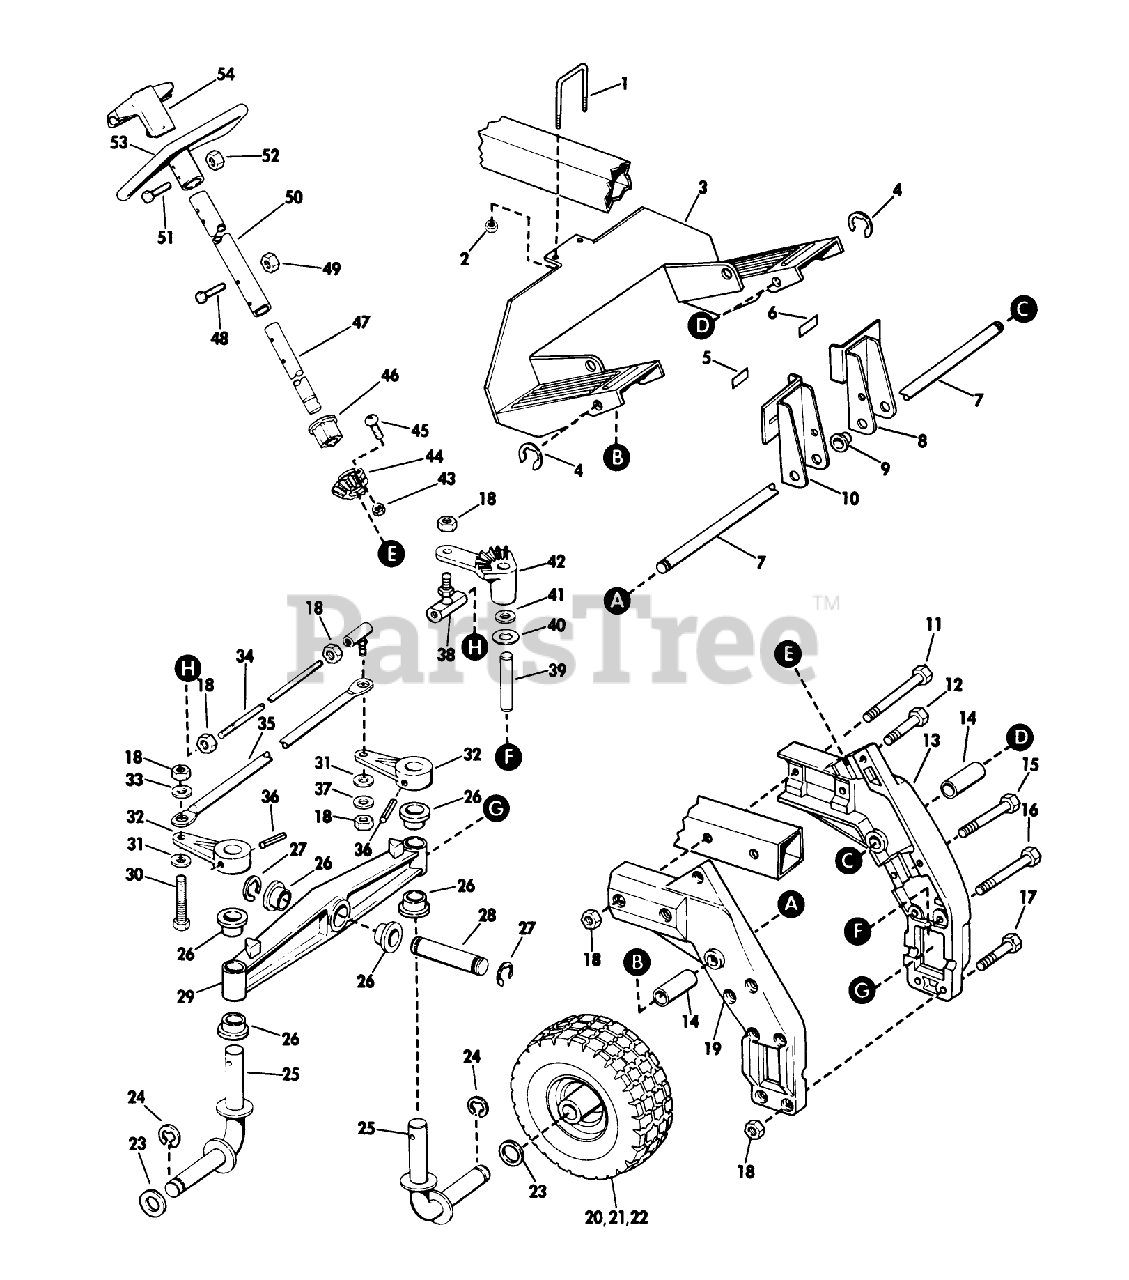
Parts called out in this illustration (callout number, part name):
30	Screw-King Pin
41	Spring Washer
49	STOP NUT
52	Nut-Steering Shaft
